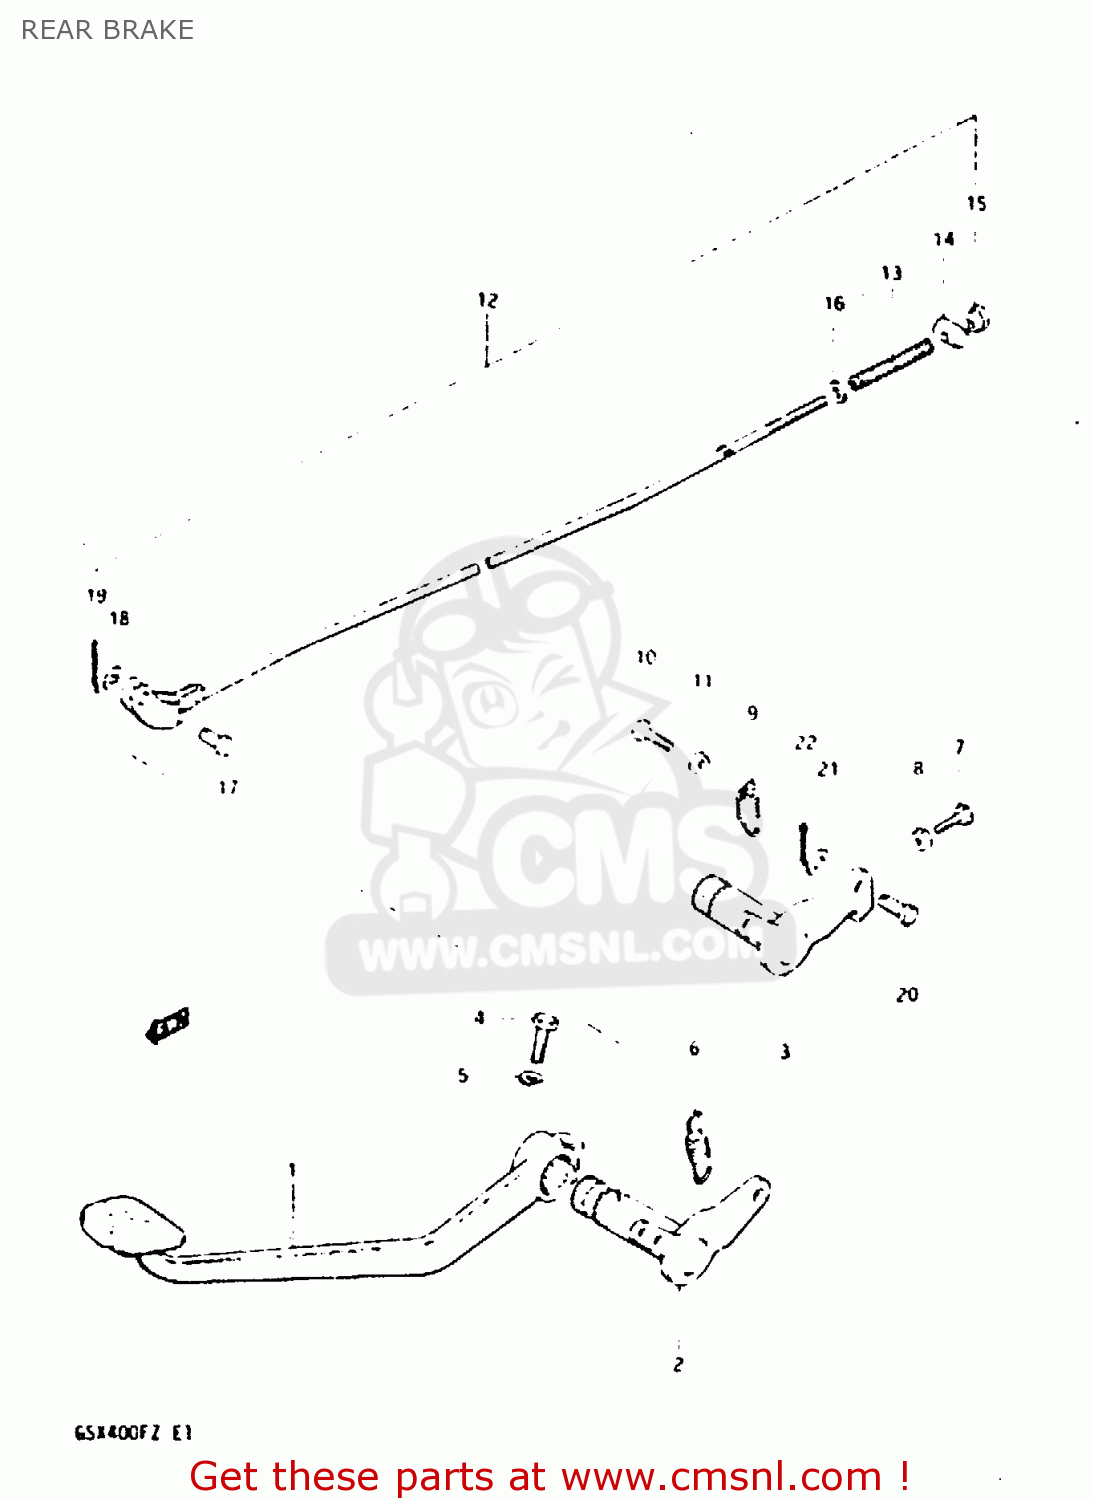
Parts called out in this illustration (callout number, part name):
1	PEDAL, BRAKE
3	ARM, BRAKE PEDAL ROD
4	BOLT
5	LOCK WASHER
9	SPRING
10	BOLT
11	NUT
20	PIN
21	WASHER
22	PIN
